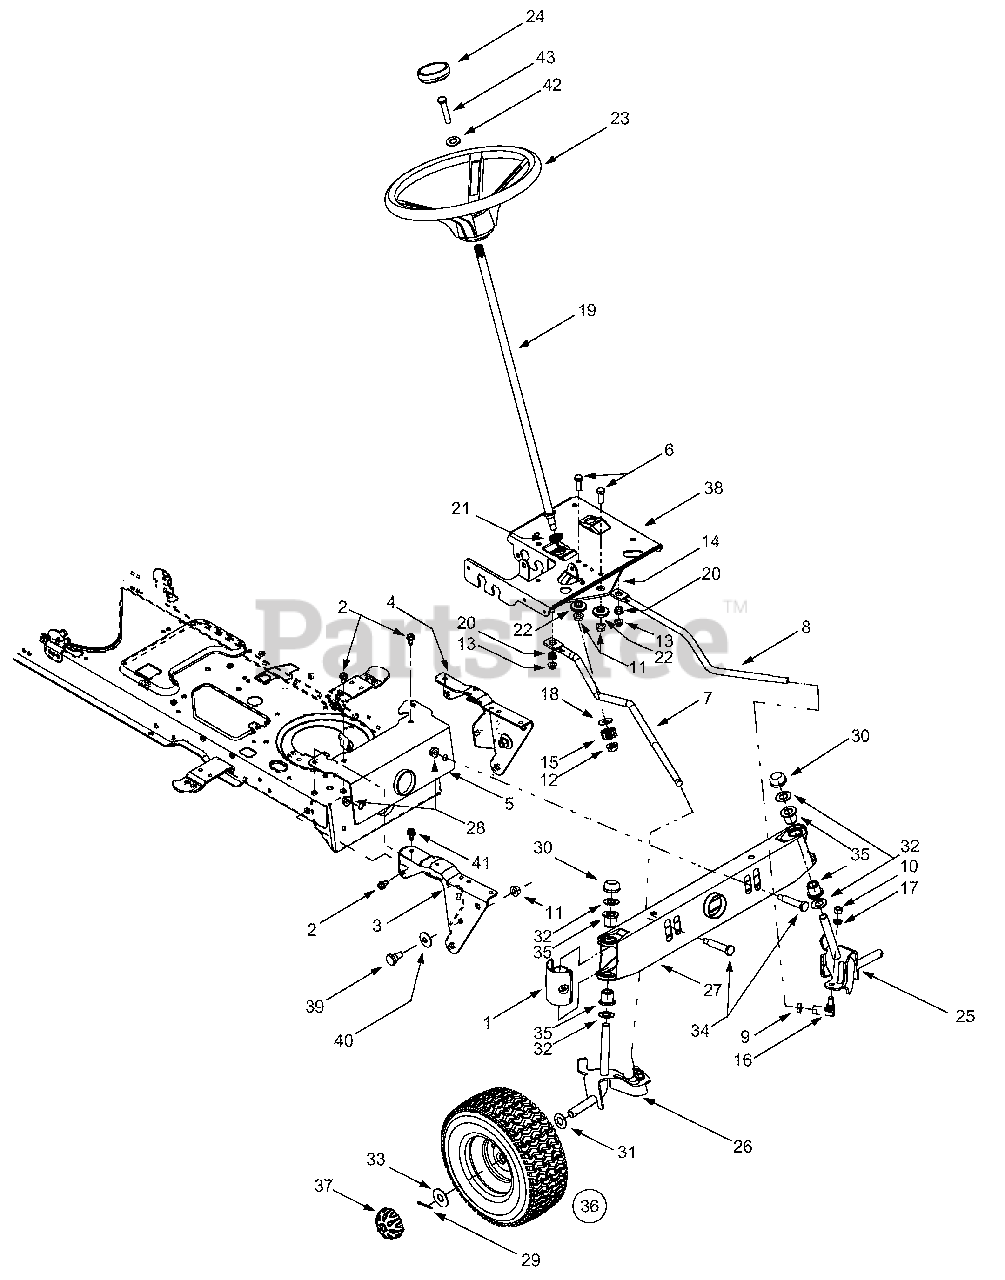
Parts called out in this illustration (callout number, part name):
1	Pivot Bar End Cap
2	Self-tapping Screw, 16-18 x .625
6	Hex Cap Screw, 3/8-16 x 1 (Grade 5)
7	RH Drag Link
8	LH Drag Link
9	Jam Nut, 7/16-20 (Grade 2)
10	Hex Nut, 3/8-24 (Grade 2)
11	Flange Lock Nut, 3/8-16
12	Flange Lock Nut, 7/16-20
13	Flange Lock Nut, 5/16-18
14	Steering Gear, 11/90 Ratio
15	Steering Pinion Gear
16	Ball Joint, 7/16-20
17	Lock Washer, 3/8
18	Flat Washer, .51 x 1.12 x .06
19	Steering Shaft, .625 OD x 24.4
20	Plastic Bushing, .38 ID
21	Hex Flange Bearing, 5/8
22	Shoulder Spacer, .38 ID
23	Steering Wheel, 13.25
24	Steering Wheel Cap, Round
25	LH Axle Assembly, .625 Diameter
26	RH Axle Assembly, .625 Diameter
28	Flange Lock Nut, 3/8-16
29	Cotter Pin
30	Push Cap, .625
31	Flat Washer, .64 x 1.0 x .12
32	Flat Washer, .64 x 1.24 x .06
33	Flat Washer, .635 x 1.589 x .06
34	Shoulder Screw, .5 x 2.2, 3/8-16
35	Flange Bearing, .632 ID x .937 OD
36	Wheel Assembly Complete, 15 x 6 x 6
37	Hub Cap
39	Shoulder Screw, 3/8-16
40	Bell Washer, .39 x 1.13 x .062
41	Self-tapping Screw, 5/16-18 x .75
42	Bell Washer, .34 x .872
43	Hex Bolt, 5/16-18 X 1
